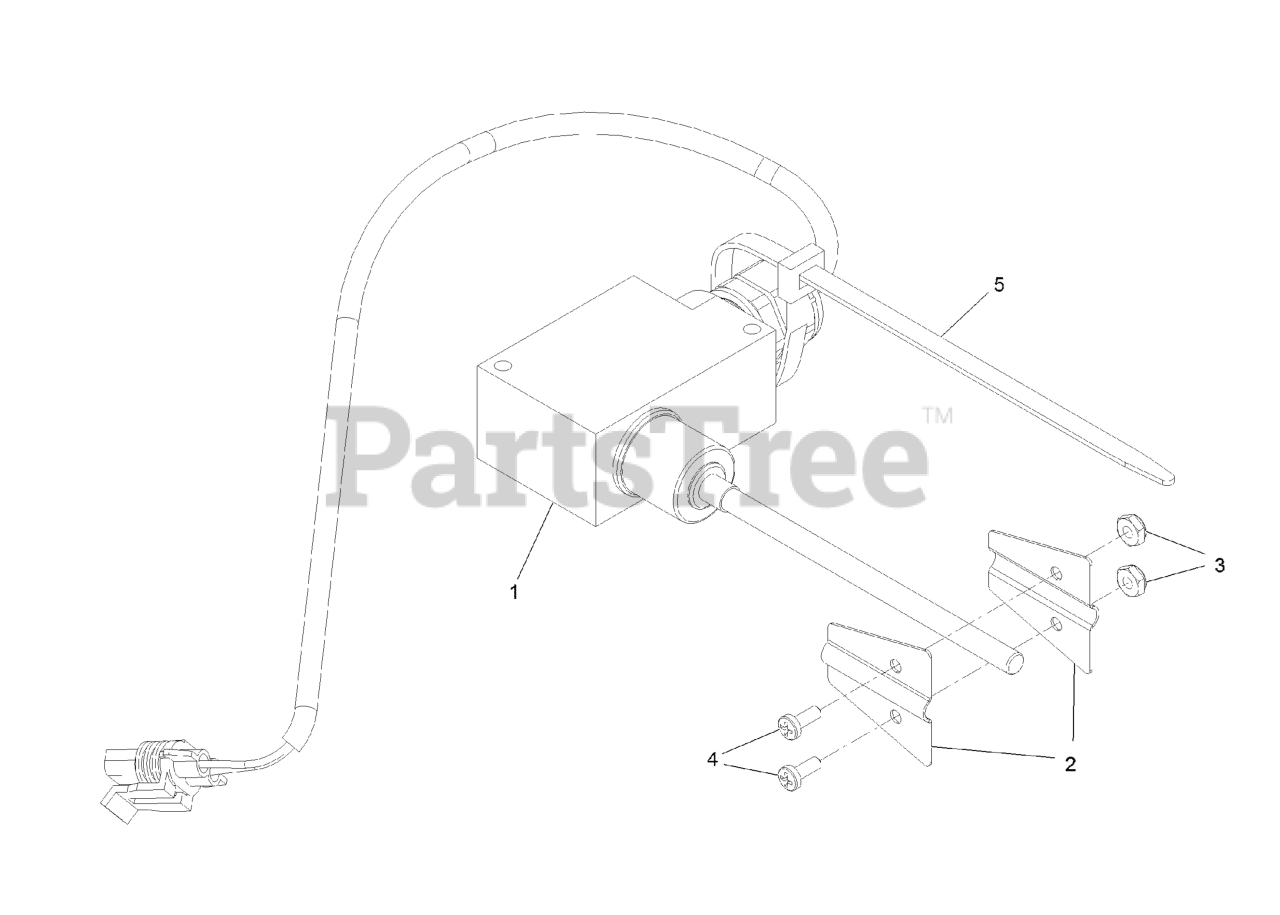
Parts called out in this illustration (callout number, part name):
1	FILL SENSOR WIRE KIT
2	FLAG- SENSOR, FILL
3	NUT-HEX
4	SCREW-PAN
5	TIE-PLASTIC
